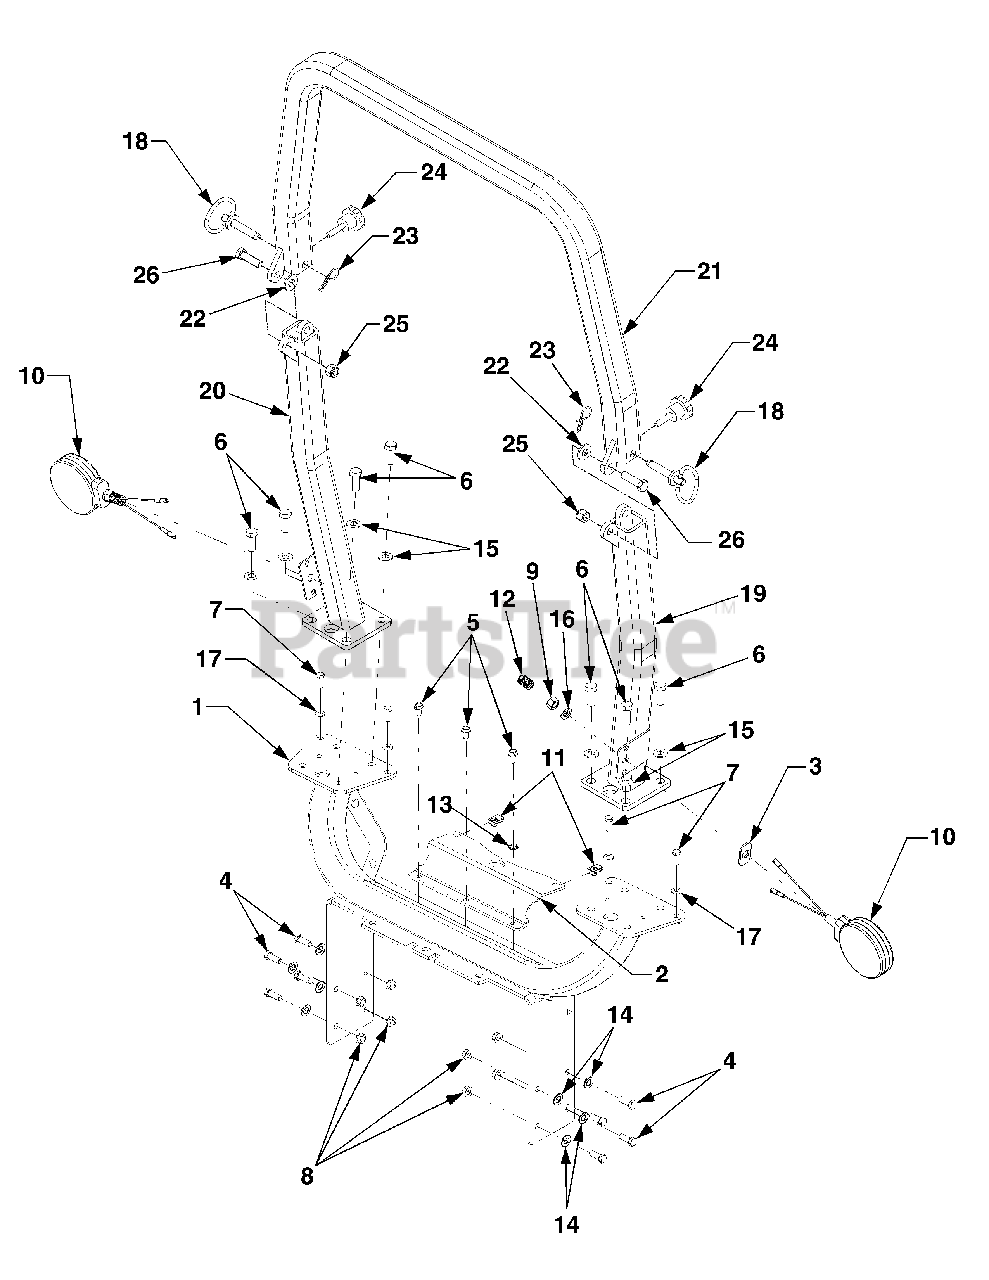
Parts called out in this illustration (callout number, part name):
1	Rops, Lower
5	Screw, Hex Wash. Hd. Tapp 5/16-18 x .75
6	Screw, Hex Cap, 1/2-13 x 1.25 GR5
7	Screw, Hex Cap, 5/16-18 x .875 GR5
8	Nut, Hx. Insert Flange Lck, 3/8-16 GRF
9	Nut, Hex, 1/2-20 GR5
10	Light, Hazard
11	Nut, Speed, 5/16-18
12	Conduit 12in
13	Washer, Ext. Tooth Lock, 3/8
14	Washer, Flat, .375 x .738 x .063
15	Washer, Flat, .51 x 1.0 x .060
16	Washer, Lock, 1/2
17	Washer, Flat, .345 x 1.0 x .10
22	Washer, flat
23	Pin, Internal Cotter
24	Knob Assembly
25	Nut, Hex Insert Lock, 1/2-13
26	Screw, Hex Cap, 1/2-13 x 1.75 GR5 ...
